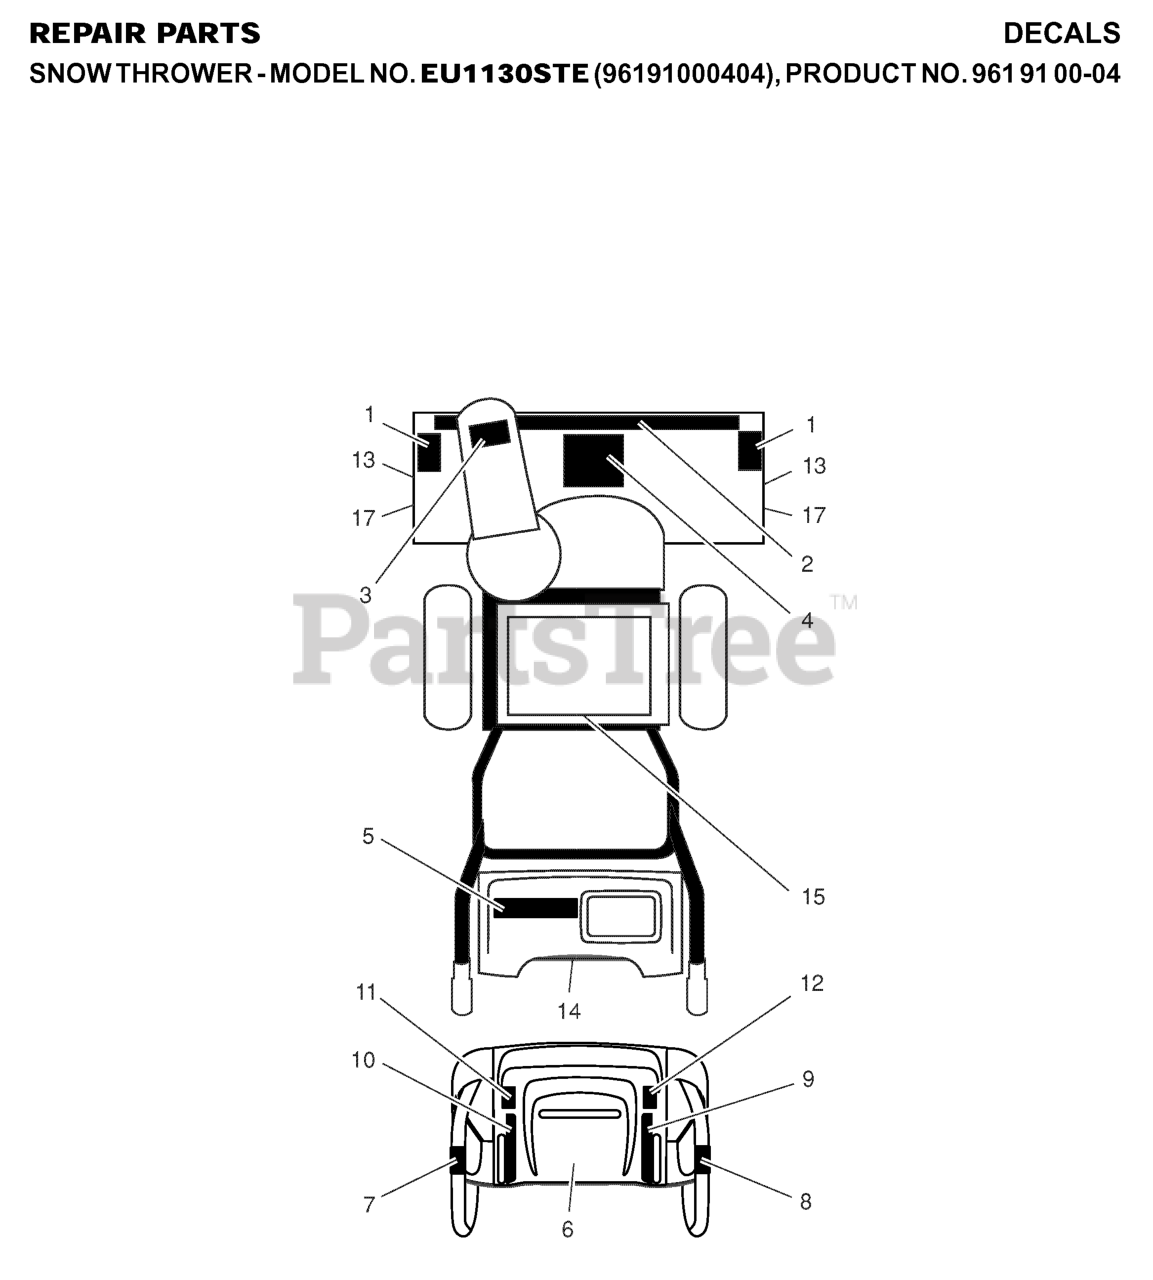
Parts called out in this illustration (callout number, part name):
1	DECAL.AUGER.SAFETY.
3	DECAL.CHUTE.SAFETY.
4	DECAL.AUGER."
6	DECAL.CONSOLE.INSTRUCTION
10	DECAL.REM.DEFLECTOR.LT
11	DECAL, LH TRIGGER
12	DECAL, RH TRIGGER
14	DECAL.FENDER
15	DECAL.BELT.GUARD.
17	DECAL, HUSQVARNA
